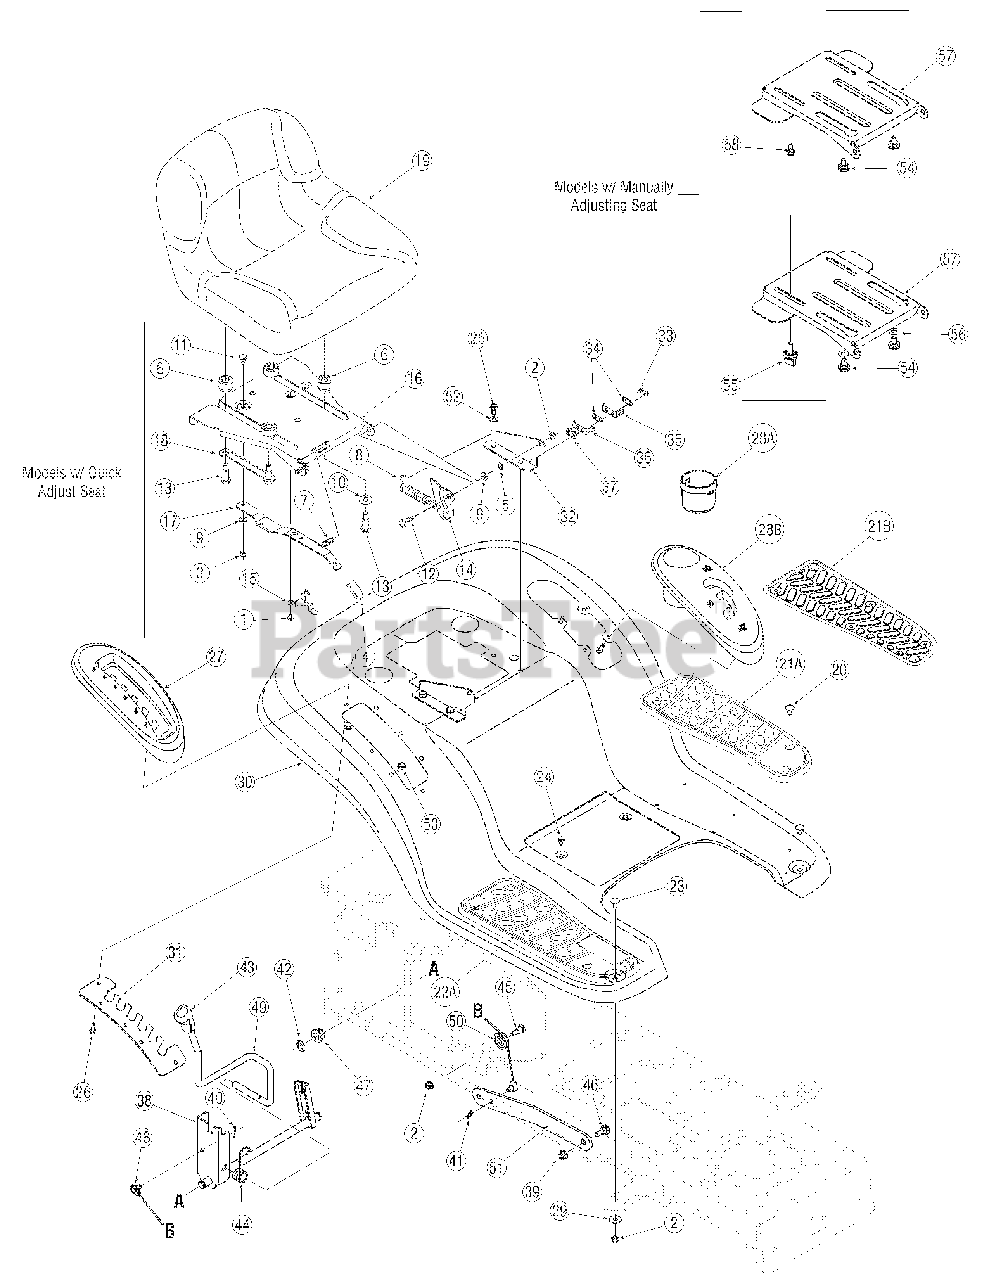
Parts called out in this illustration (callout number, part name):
1	Screw, #10-16 x.375 (if equipped)
2	Nut, Flange Lock, 5/16-18, GrF
3	Nut, Flange Lock, 1/4-20 (if equipped)
4	Seat Adjuster Grip (if equipped)
5	Nut, Speed,.3125 ID (if equipped)
6	Spacer (if equipped)
7	Compression Spring,.41 x 1.5 (if equipped)
8	Spring, Extension,.84 Dia. X 4.6
9	Wash, Flat,.344 x.688 x.065 (if equipped)
10	Wash, Flat,.531x 1.062 x.134 (if equipped)
11	Screw, Shld, .340 x.285, 1/4-20 (if equipped)
12	Screw, Shoulder,.437 x.268
13	Screw, Should,.50 x.925, 3/8-16 (if equipped)
14	Seat Bracket, Lift
15	Seat Stop (if equipped)
18	Seat Adjustment Selector (if equipped)
19	Medium Back Seat, Yellow
20	Ratchet Clip
23	Bolt, Carriage, 5/16-18,.75, Gr1
24	Screw, 1/4-20, 0.500
25	Screw, 5/16-18, 0.625
26	Screw, 1/4-15, 0.750 (if equipped)
27	Cover, Lift Lever (if equipped)
29	Washer, Flat,.344 x 1.0 x.063
33	Screw, #8-18 x.50
34	Plate, Insulator
35	Spring Switch, Outer
36	Spring Switch, Inner
37	Plate, Insulator Boss
39	Nut, Flange Lock, 3/8-16, GrF
40	Pin, Cotter,.072 Dia. x 1.13
41	Pin, Cotter, 3/32, 1.0
42	Ring, E Type,.625 Dia.
43	Grip, Handle, 1/2
44	Spring, Torsion
45	Screw, 5/16-18 x.620 Gr2
46	Scr.,Shldr, .625 x.165,(42" deck)
46	Screw, Shld,.50 x.27, (46" deck)
47	Bearing, Hex Flange
48	Cable, Lift, 16.16
49	Handle, Lift
50	Pulley, Roller
52	Lock Washer, 5/16
53	Screw, 5/16-12
54	Shoulder Screw (if equipped)
55	Knob, 3/8-16 (if equipped)
56	Flat Washer, .406 x .875 x .059 (if equipped)
58	Hex Head Washer Screw, 3/8-16 (if equipped)
